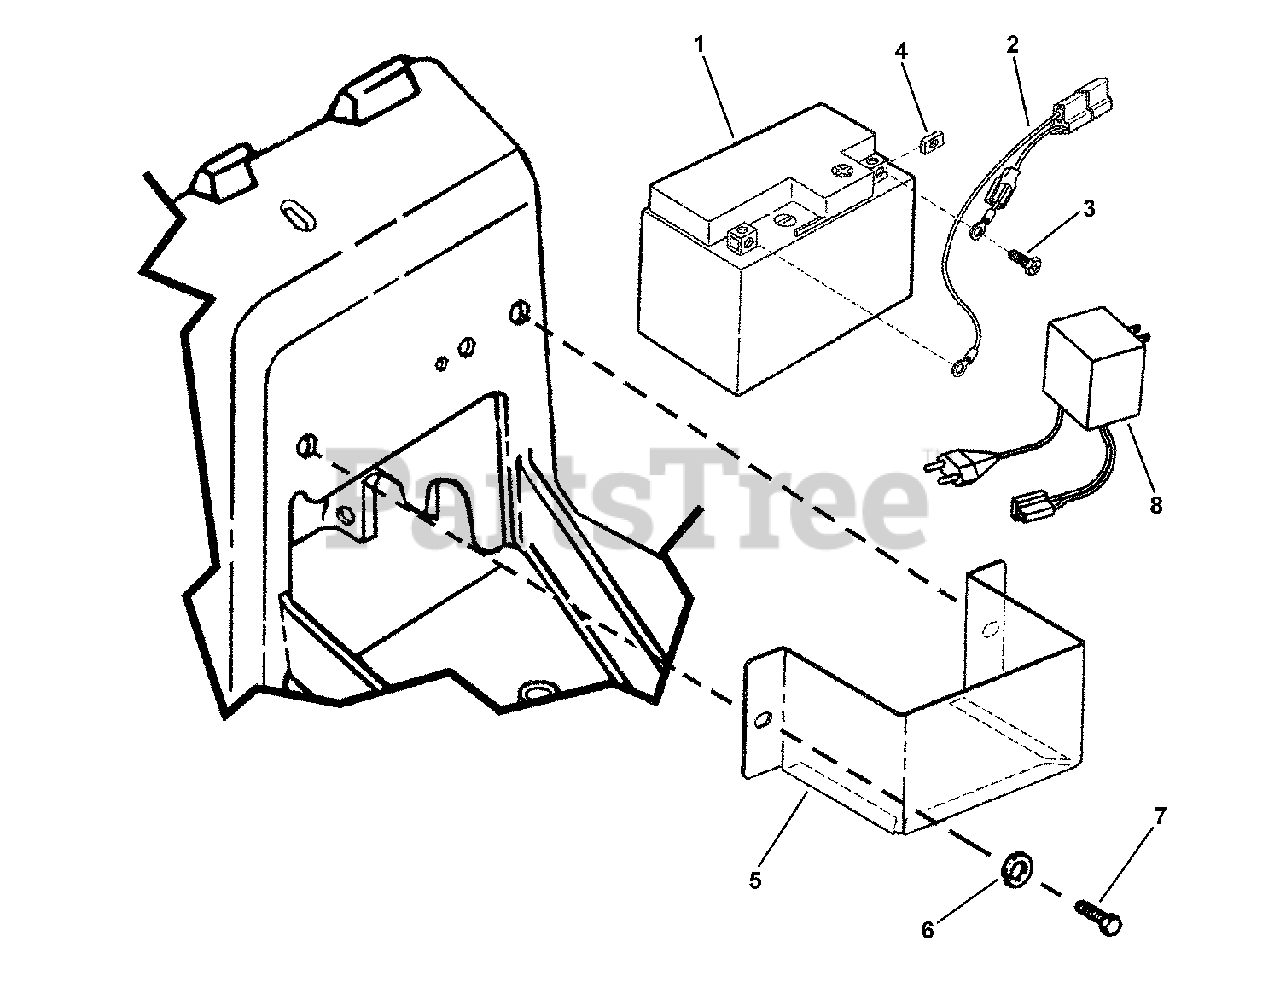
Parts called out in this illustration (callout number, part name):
1	BATTERY, 12 Volt, 35 CCA
2	HARNESS, Battery
3	SCREW, M5 x 10mm Cross Recess Pan Head
4	NUT, Battery Terminal
5	BRACKET, Battery Support
6	WASHER, 1/4" Split Lock
7	SCREW, 1/4-20 x 3/4" Hex Head Cap, GR 5
8	CHARGER, Battery, 230v/12v
